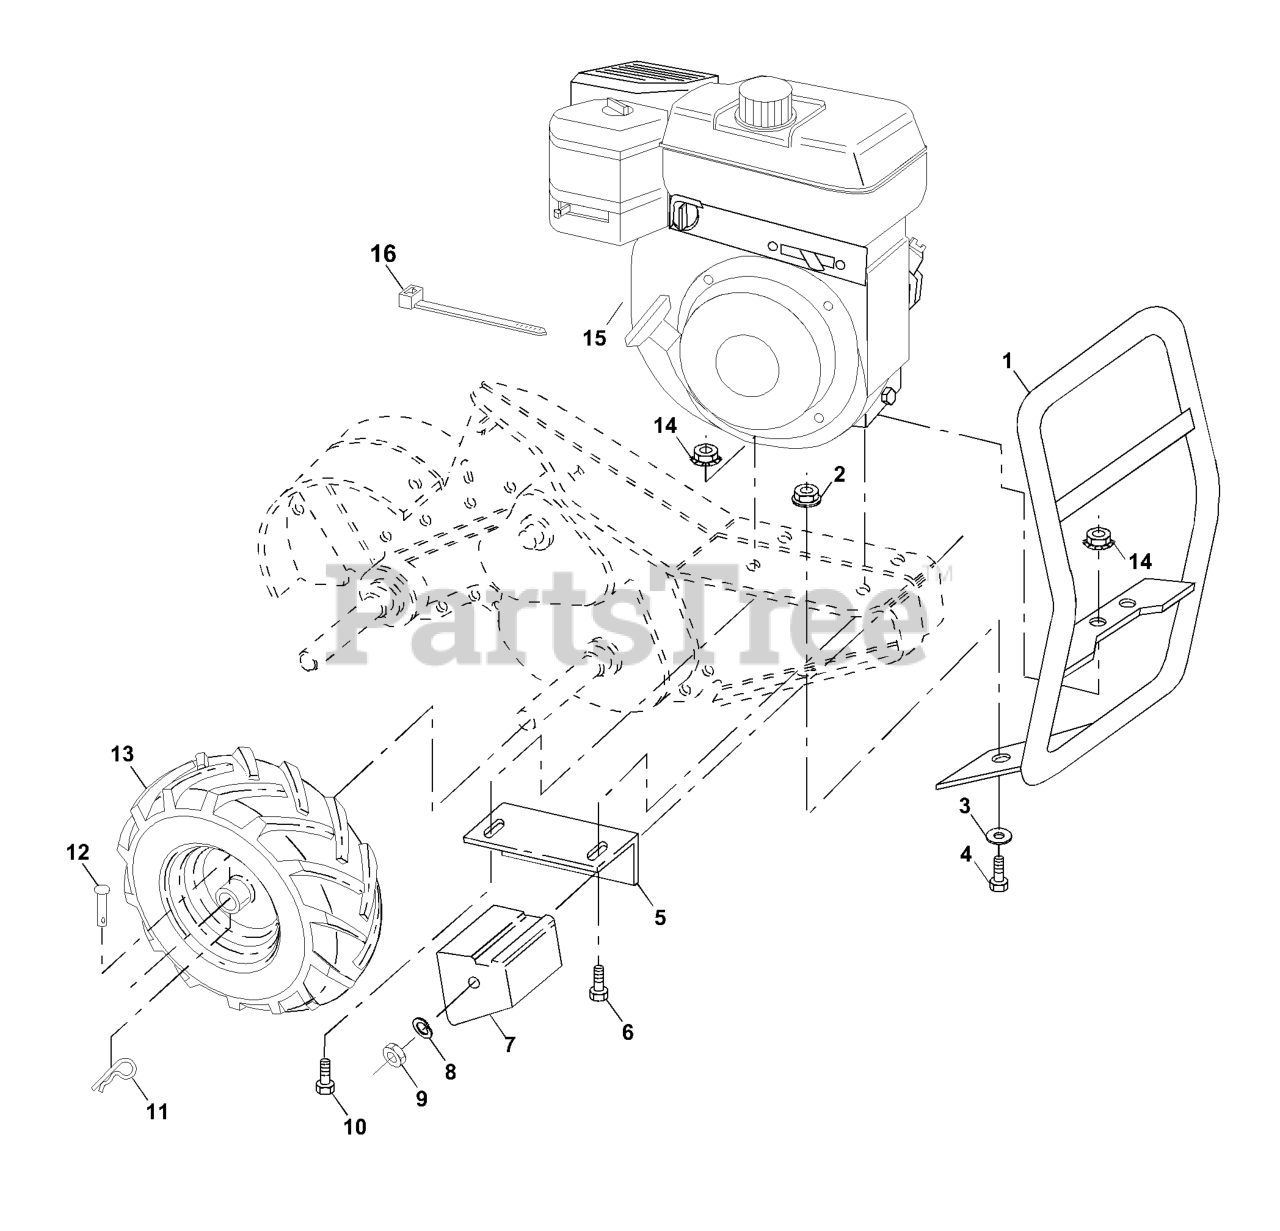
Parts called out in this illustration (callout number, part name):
1	BUMPER
2	LOCKNUT-FLANGE 5/16-18
3	WASHER
4	BOLT
5	DNO BRACKET RH CRT
6	Bolt, Hex 5/16-18 x 2
7	COUNTERWEIGHT, RH
8	WASHER, LOCK 3/8
9	NUT.HEX.3/8-16UNC
10	BOLT
11	RETAINER M
12	RIVET,DRILLED
13	TIRE.16X4-8.CHEVRON.TILLER
13	RIM
13	VALVE STEM LT
14	NUT
15	Engine, Briggs & Stratton
16	TIE GUIDE
